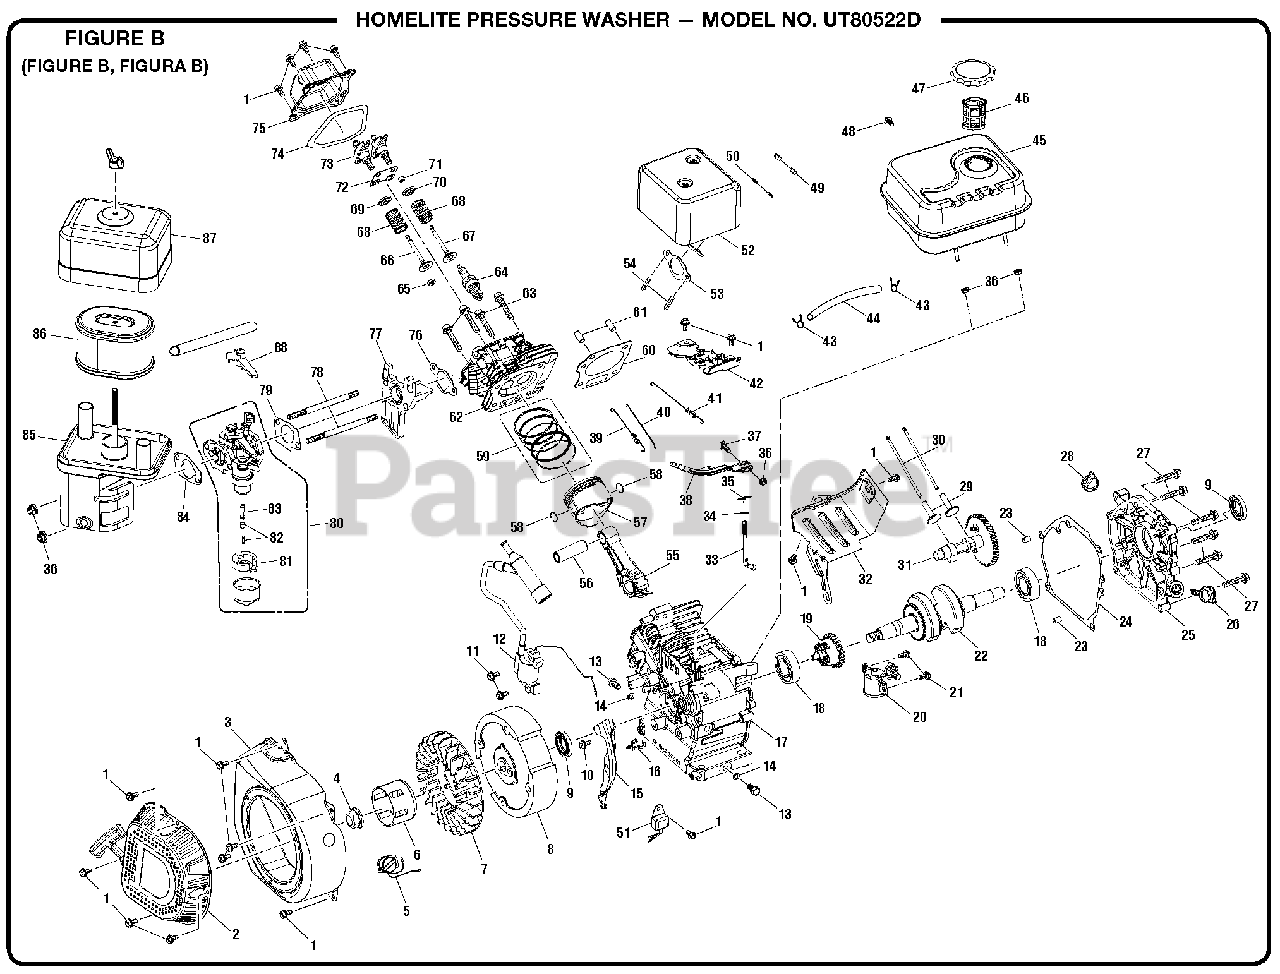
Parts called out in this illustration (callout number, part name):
2	Recoil Starter Assembly
5	Switch Assembly
6	Starter Pulley
8	Flywheel Assembly
12	Ignition Coil Assembly
13	Drain Plug Bolt
15	Lower Shield
17	Crankcase Assembly
18	Ball Bearing
19	Governor Gear Assembly
20	Engine Oil Sensor
22	Crankshaft Assembly
24	Crankcase Gasket
25	Crankcase Cover Assembly
29	alve Lifter
31	Camshaft Assembly
33	Governor Arm
38	Governor Support Assembly
39	Throttle Valve Return Spring
40	Governor Rod
41	Governor Spring
42	Upper Shroud Assembly
43	Fuel Line Clip
45	Fuel Tank Assembly
46	Fuel Filter
47	Fuel Tank Cover
50	Spring Washer
51	Oil Protector
52	Muffler Assembly
53	Exhaust Outlet Gasket
55	Connecting Rod Assembly
58	Piston Pin Clip
59	Piston Rings
60	Cylinder Head Gasket
62	Cylinder Head
66	Intake Valve
67	Exhaust Valve
68	Valve Spring
69	Valve Spring Seat
70	Exhaust Valve Retainer
71	Valve Rotator
72	Guide Plate Assembly
73	Rocker Assembly
74	Cylinder Head Gasket
75	Cylinder Head Cover Assembly
76	Carburetor Insulator Gasket
77	Carburetor Insulator Plate
79	Carburetor Gasket
80	Carburetor Assembly
84	Air Cleaner Gasket
85	Air Cleaner Base
86	Air Cleaner Element
87	Air Cleaner Case Cover
88	Choke Lever
